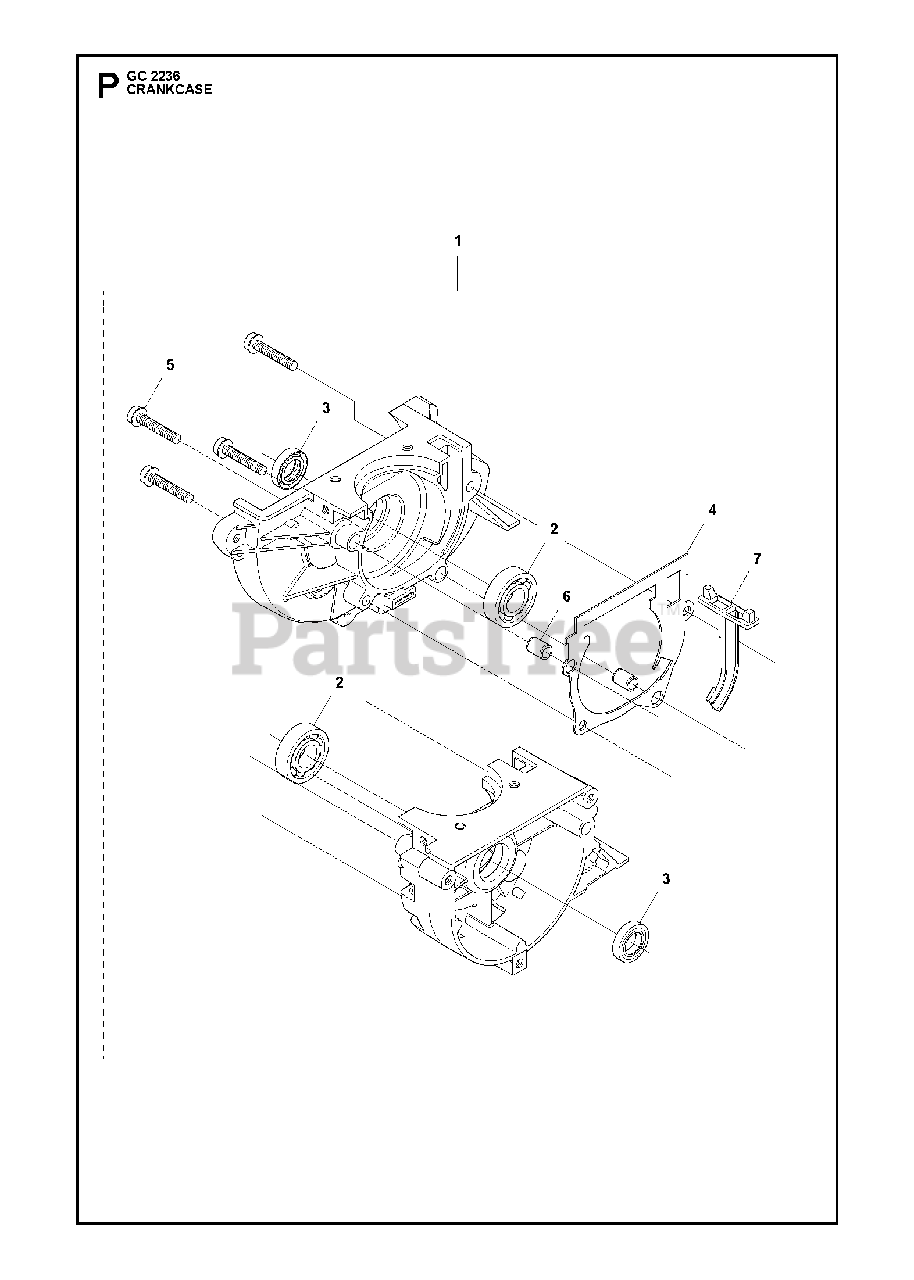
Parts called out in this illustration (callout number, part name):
1	CRANKCASE CPL
2	BALL BEARING
3	SEALING RING
4	GASKET
5	SCREW
6	SLEEVE
7	INSERT, CARTER
